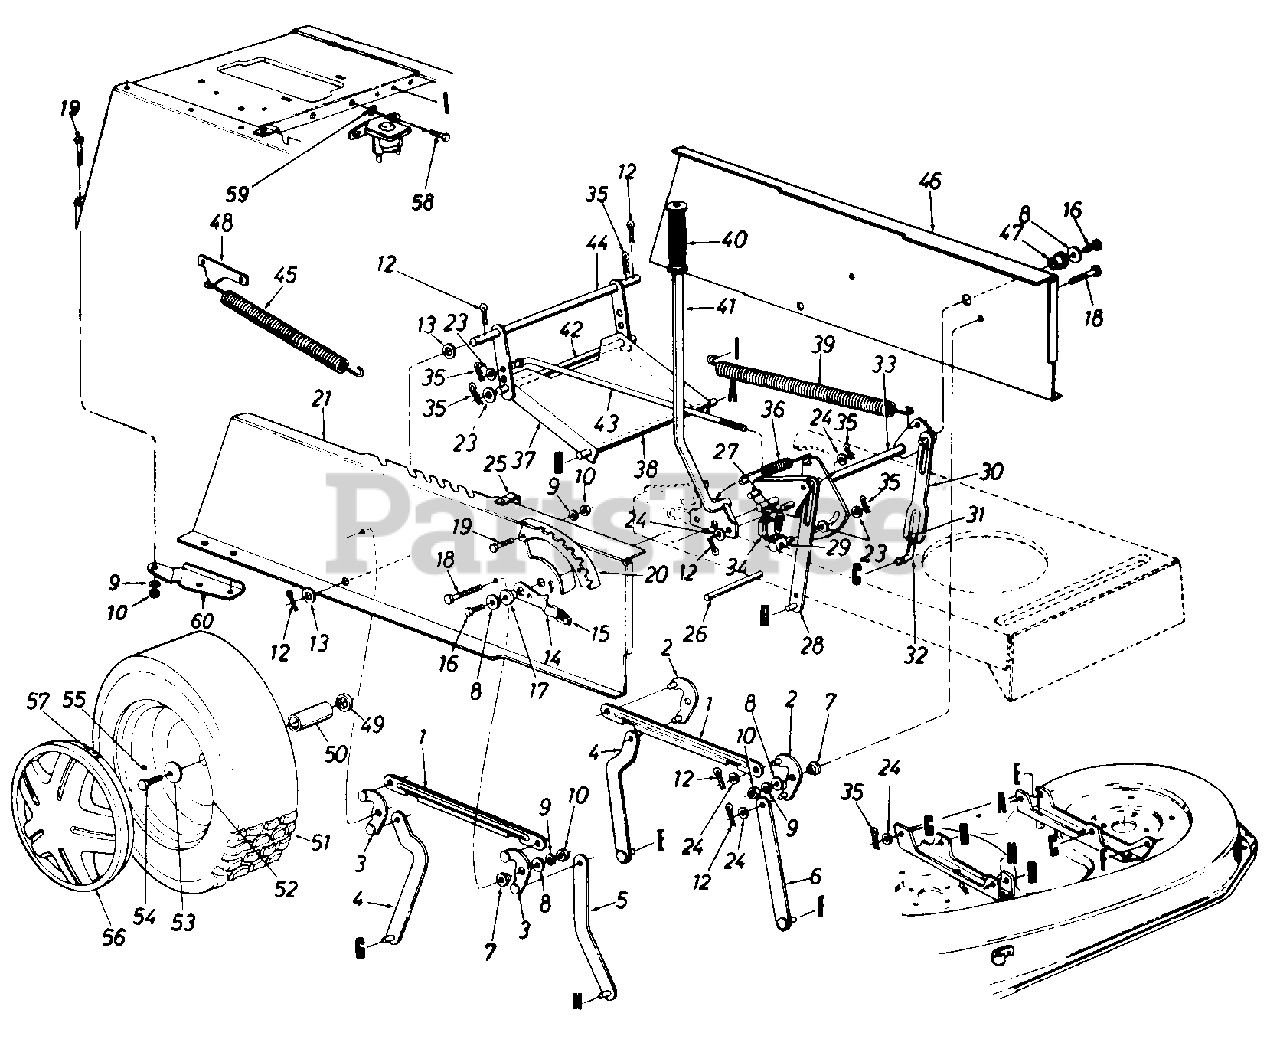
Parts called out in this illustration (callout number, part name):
1	Connecting Rod
2	Pivot Link Ass'y. L.H.
3	Pivot Link Ass'y. R.H.
7	Shld. Spacer .3/8" I.D.
8	Fl-Wash. .344" I.D. x 1.125"
9	L-Wash. 5/16" I.D.
10	Hex Nut 5/16-18 Thd.
12	Cotter Pin 1/8" Dia.
13	Fl-Wash. .635" I.D. x 1.0" O.D.
14	Deck Lift Stop
15	Knob
16	Hex TT-Tap Scr. 5/16-18 x .75"
17	Flange Brg. .63" I.D.
18	Hex TT-Tap Scr. 5/16-18 x .875"
19	Hex Bolt 5/16-18 x .75" Lg.
20	Index Brkt.
21	Upper Frame R.H.
23	Fl-Wash. .385" I.D. x .87" O.D.
24	Fl-Wash. .531" I.D. x .93" O.D.
25	Clamp
26	Running Board Rod
27	Hex Tap Scr. #12 x .375"
31	Hex Nut 1/2-20 Thd. (Grade 5)
32	Lift Link Adjuster
33	Lift Shaft Ass'y.
34	Safety Switch (Deck)
35	Inter. Cotter Pin 3/8" Dia.
36	Extension Spring
37	Stabilizer Bracket
38	Shaft 1/2" Dia. x 10.28" Lg.
39	Extension Spring
40	Grip
41	Deck Lift Handle Ass'y.
42	Shaft 9.34" Lg.
43	Disengagement Rod
44	Stabilizer Shaft Ass'y.
45	Extension Spring
46	Upper Frame L.H.
47	Flange Brg. .632" I.D.
48	Deck Spring Brkt.
49	Fl-Wash. 76" I.D. x 1.49" O.D.
50	Sleeve .75" I.D. x 1.0" O.D.
52	Wheel Rim Only
53	Bell-Wash. .345" I.D. x .88"
54	Hex L-Bolt 5/16-24 x .75" Lg.
55	Air Valve
56	Hub Cap
57	Spring Clip
58	Hex Wash. Hd. TT-Tap Scr. 1/4-20 Thd.
59	Ext. L-Wash. 1/4" I.D.
